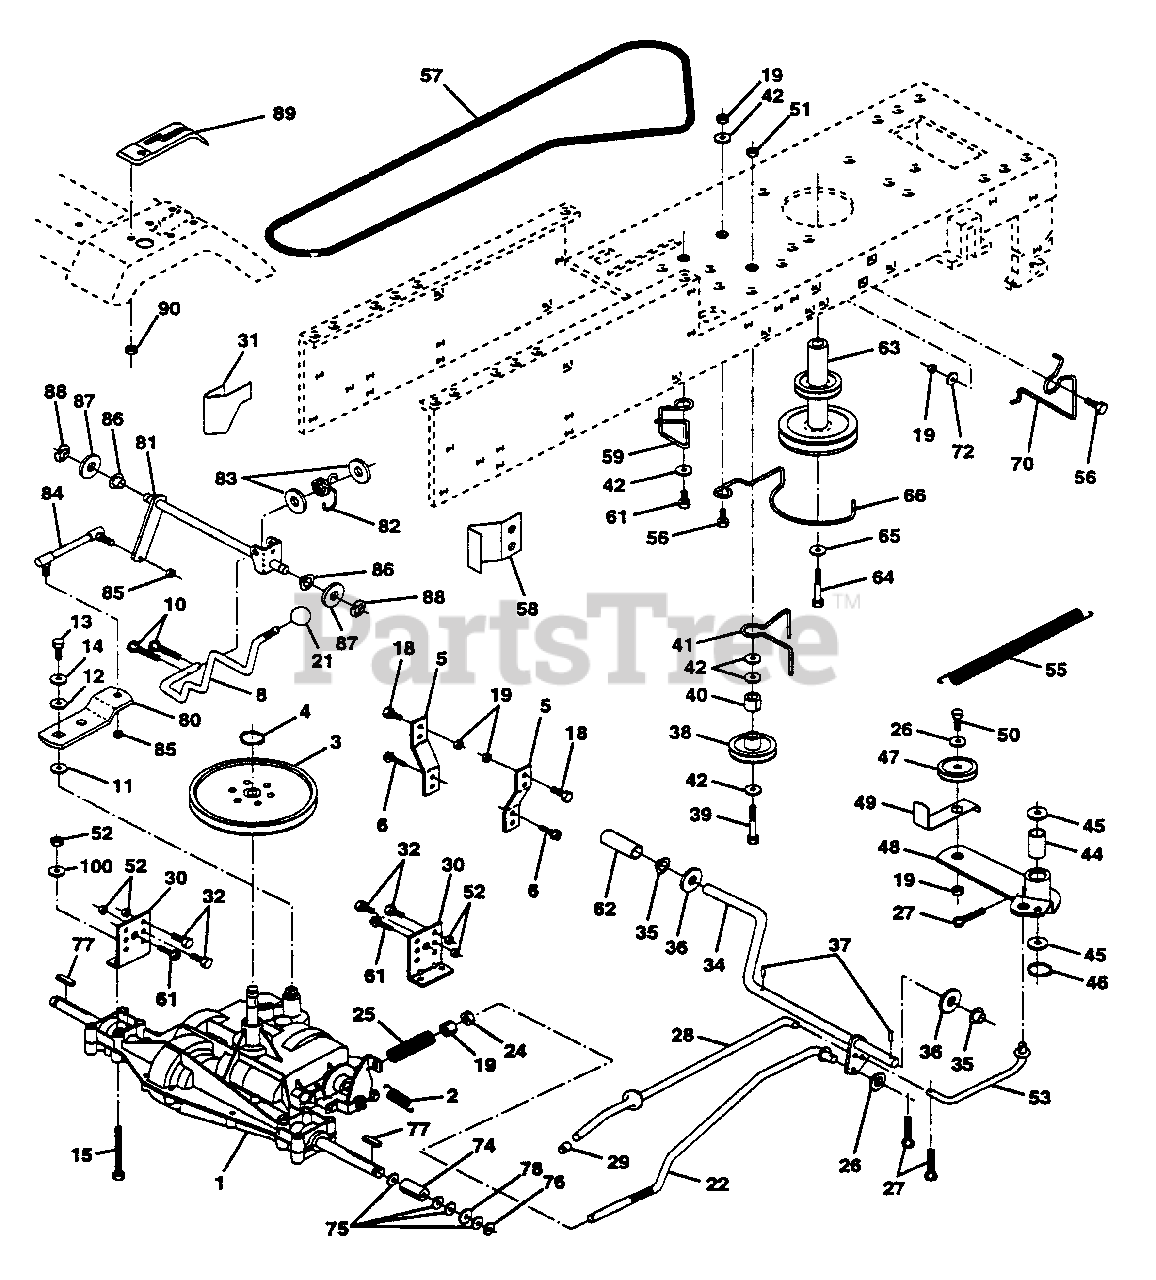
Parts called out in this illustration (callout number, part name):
1	Transaxle 6sp Model No. 4360-79
2	Spring Return Brake T/a Zinc
3	Pulley Transaxle 18" tires
4	Ring Retainer # 5100-62
5	Strap Torque 30 Degrees
6	Screw Tndrol 5/16-18 X 3/4 TYT
7	Bracket Saddle Shift
8	Rod Shifter
9	Washer 15/32 x 3/4 x 16 Ga.
10	Pin Cotter 1/8 X 1 Cad
11	Washer Plate Shf 388 Sq Hole
12	Washer 9/32 X 3/4 X 10 Ga
13	Bolt 1/4-28 Unf Gr.8 w/Patch
14	Washer Lock Hvy Helical 1/4
15	Bolt Fin Hex 5/16 - 18 UNC x 2.75
17	Strap Torque LT
18	Bolt Fin Hex 3/8-16unc X 1 Gr. 5
19	Nut Hex Lock W/Ins 3/8-16 Unc
20	Screw Thdrol 5/16-18 X 3/4 TYT
21	Knob Duckhead 1/2-13 UNC
22	Rod Brake Blk Zinc 27 326
23	Nut Lock Hex W/wsh 3/8-16unc
24	Nut Hex Jam 3/8-16 Unc
25	Spring Rod Brake 2 00 Zinc
26	Washer 13/32 X 13/16 X 16 Ga
27	Pin Cotter 1/8 X 3/4 Cad
28	Rod Brake Parking LT
29	Cap Brake Parking Black
30	Bracket Mtg Transaxle
31	Keeper Belt LH LT 14 Ga
32	Bolt Hex Hd 5/16-18unc X 3/4
33	Nut Hex W/Ins Lock 5/16-18
34	Shaft Asm Pedal Foot 1 930
35	Bearing Nylon Blk 629 Id
36	Washer 21/32 X 1 X 16 Ga
37	Pin Roll 3/16 X 1"
38	Pulley Idler Flat
39	Bolt Fin Hex 3/8-16unc X 2-3/4
40	Spacer Split 395 X 59 Bzp
41	Keeper Belt Retainer
42	Washer 13/32 X 13/16 X 12 Ga
43	Nut Lock Hex W/Ins 3/8-16 Unc
44	Bearing Nyl 503 X 628 X 1 25
45	Washer Hardened
46	Ring Klip #t5304-50
47	Pulley Idler V Groove Plastic
48	Bellcrank Asm Clutch
49	Retainer Belt Style Spring
50	Bolt Hex Hd 3/8-16unc X 1-1/2
51	Nut Crownlock 3/8-16 Unc
52	Washer 13/32 X 13/16 X 16 Ga
53	Link Clutch 7 66
54	Pin Cotter 1/8 X 3/4 Cad
55	Spring Return Clutch 6 75
56	Pin Cotter 1/8 X 3/4 Cad
57	V-Belt Ground Drive 95 25 42"
58	Keeper Belt RH LT Pnt/zinc 16g
59	Keeper Belt Chassis Span Ctr
60	Washer 13/32 X 13/16 X 12 Ga
61	Screw Thdrol 3/8-16x3/4 Ty-tt
62	Cover Pedal Blk Round
63	Engine Pulley
64	Bolt Hex 7/16-20x4 Gr 5
65	Washer Lock Hvy Hlcl Spr. 7/16
66	Keeper Belt Engine LH LT
67	Bolt Fin Hex 3/8-16unc X 1
68	Washer 13/32 X 13/16 X 12 Ga
69	Nut Crownlock 3/8-16 Unc
70	Guide Belt Mower Drive RH
71	Bolt Fin Hex 3/8-16unc X 1
72	Washer 13/32 X 1-1/4 X 12 Ga
73	Nut Crownlock 3/8-16 Unc
74	Spacer Axle
75	Washer 25/32 X 1 1/4 X 16 Ga.
76	E-ring #5133-75
77	Key Square 2 0 X 1845/ 1865
78	Washer 25/32 X 1-5/8 X 16 Ga
95	Screw Thdrol 3/8 - 16 x 3/4
100	Washer 11/32 x 314 x 16 Ga.
